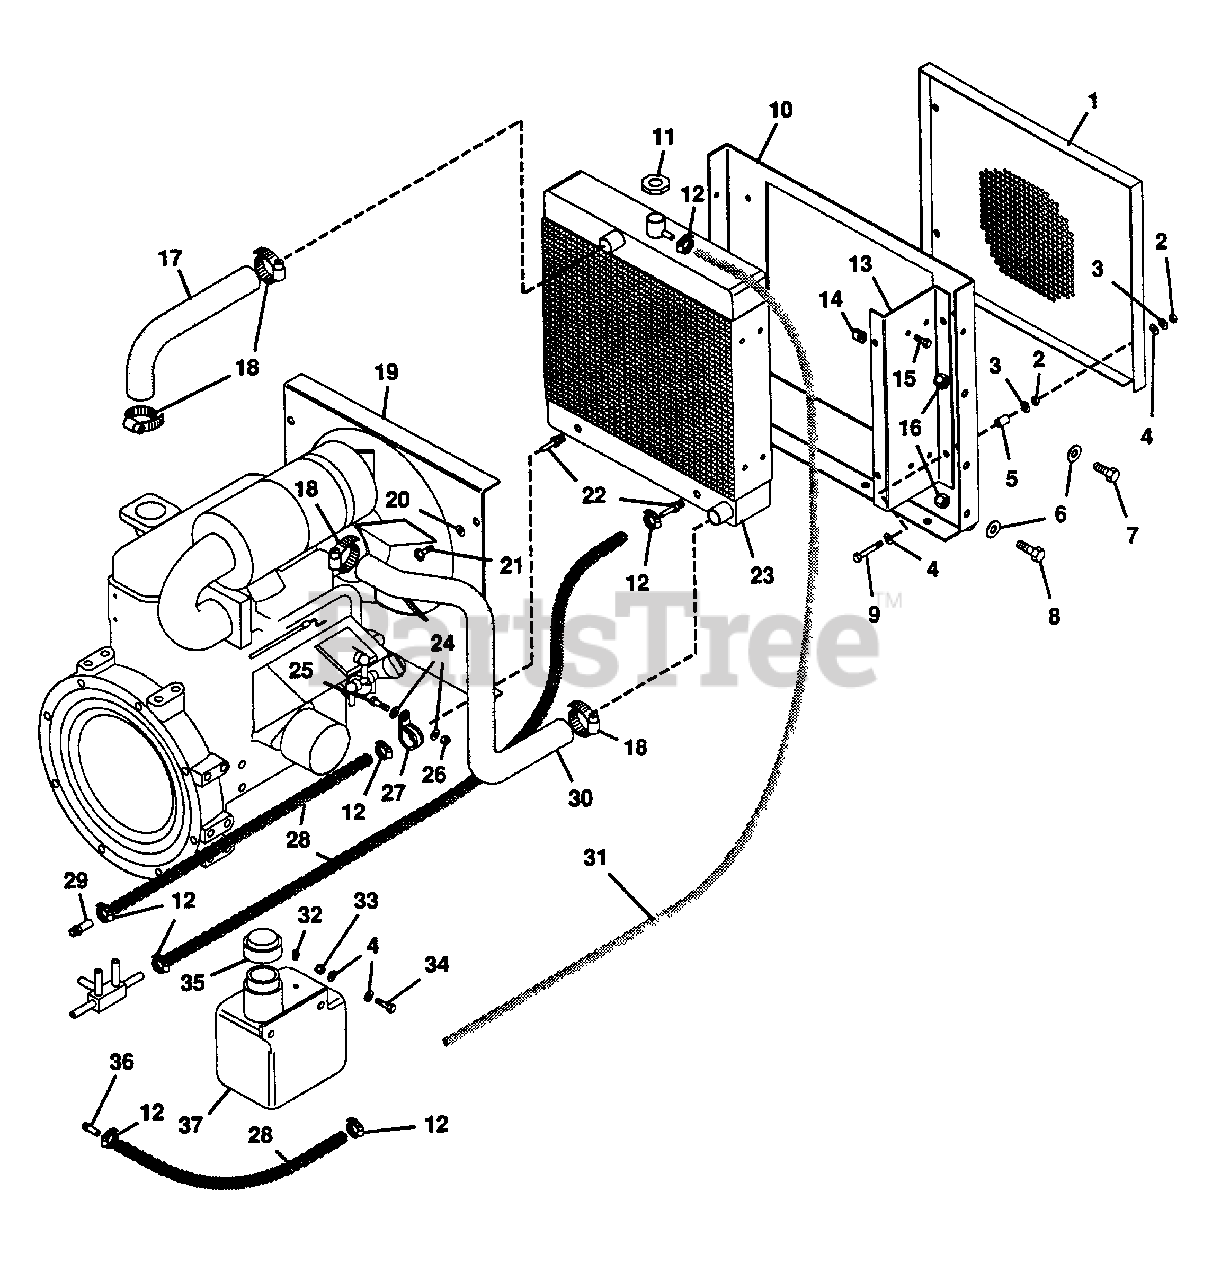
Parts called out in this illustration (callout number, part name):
1	Cover, Air
2	Nut, Hex 5/16-18
3	Washer, Lock 5/16 Reg.
4	Washer, Flat .344x.688x.065
5	Stop, Chute
6	Washer, Flat .531x1.062x.095
7	Bolt, Hex 1/2-13x1.00
8	Bolt, Hex 1/2-13x1.50
9	Bolt, Hex 5/16-18x2.00
10	Mount, Radiator
11	Cap, Radiator
12	Clamp, Hose
13	Bracket, Radiator
14	Nut, Retainer
15	Bolt, Hex 5/16-18x.50
16	Nut, Lock 1/2-13
17	Hose, Upper Radiator
18	Clamp, Hose
19	Cover, Fan
20	Washer, Flat .281x.625x.065
21	Screw, Machine 1/4-20 PHD
22	Adapter, #4404-6-6
23	Radiator, Flat Plate
24	Washer, Flat .406x.812x.065
25	Bolt, Hex 3/8-16x1.00
26	Nut, Lock 3/8-16
27	Clamp, Steel .625
28	Hose, Hydraulic
29	Adapter, #4604-6-6
30	Hose, Lower Radiator
31	Hose, 5/16 ID
32	Plug, 1/8 Vent
33	Nut, Lock 5/16-18
34	Bolt, Hex 5/16-18x1.00
35	Cap, 1-5/8 Non-Vented(White)
36	Connector, Hose
37	Tank, Plastic 1.5 Qt.
